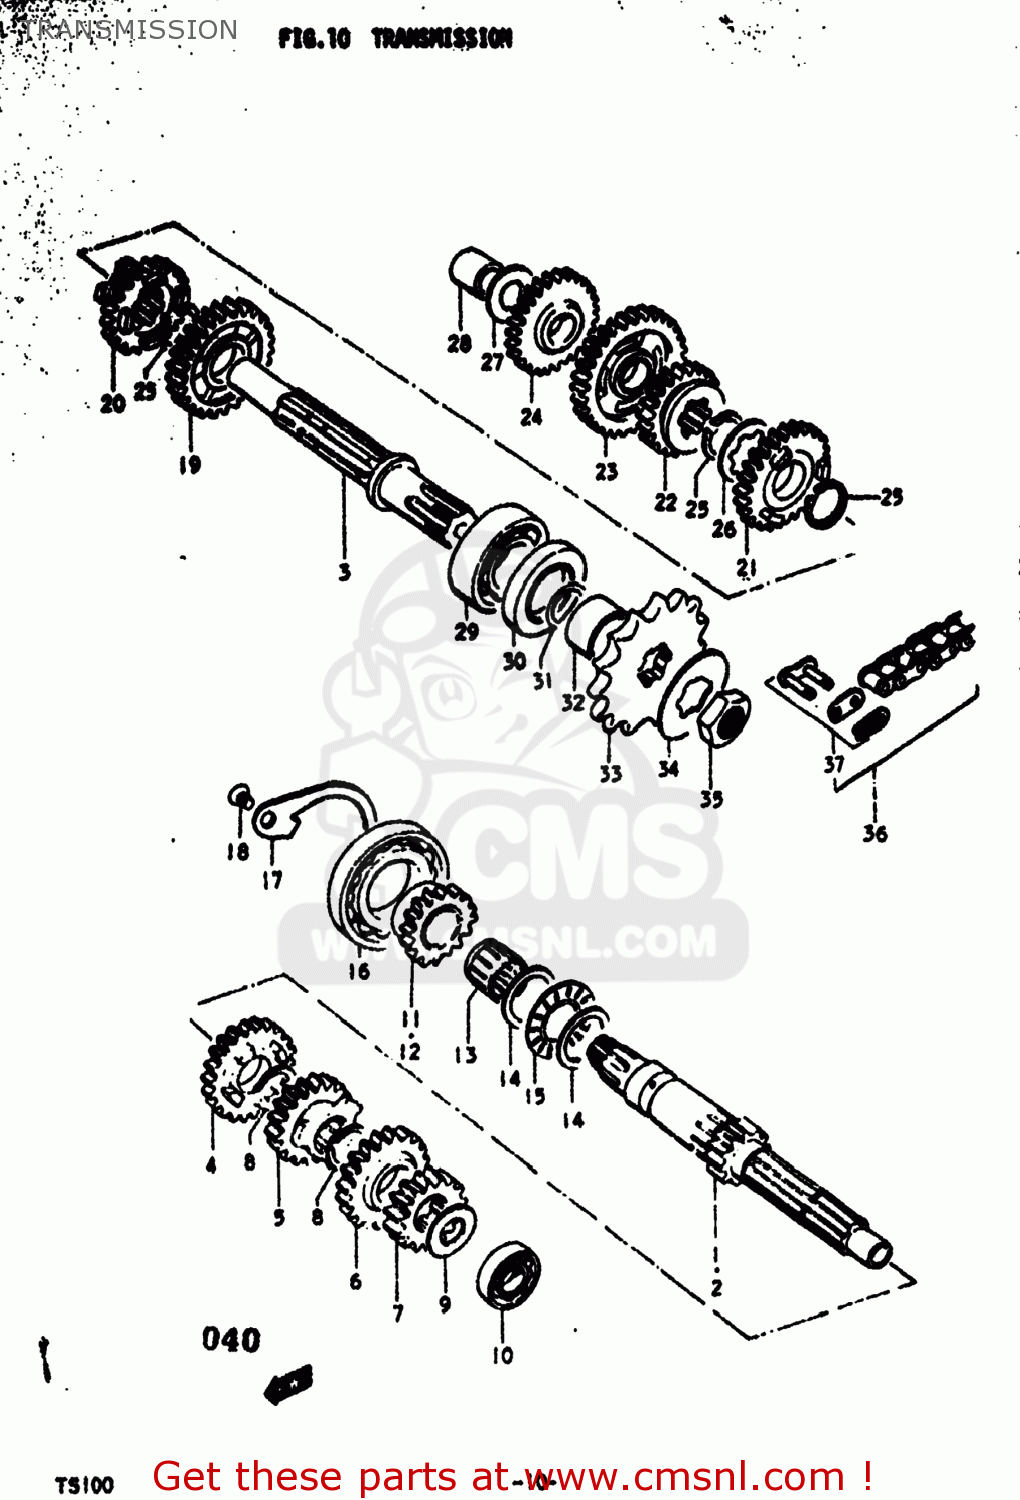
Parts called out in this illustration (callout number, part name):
1	SHAFT,COUNTER
2	SHAFT,COUNTER
3	SHAFT,DRIVE
4	GEAR,FIFTH DRIVE
5	GEAR,THIRD DRIVE
6	GEAR,FOURTH DRIVE
7	GEAR,SECOND DRIVE
8	CIRCLIP
9	WASHER
10	BEARING(12X28X8)
11	GEAR,KICK STARTER DRIVEN(NT:16
12	GEAR,KICK STARTER DRIVE
13	BEARING(19.2X23.2X19)
14	WASHER(21X30X0.8)
15	BEARING 21X35X2.8
16	BEARING
17	PLATE,COUNTERSHAFT BEARING
18	SCREW
19	GEAR,SECOND DRIVEN
20	GEAR,FOURTH DRIVEN
21	GEAR,THIRD DRIVEN
22	GEAR,FIFTH DRIVEN
23	GEAR,FIRST DRIVEN
24	GEAR,KICK STARTER IDLE
25	CIRCLIP
26	WASHER
27	WASHER
28	BUSHING
29	Bearing
30	SEAL,OIL(25X40X7)
31	O RING(D:1,ID:19.5)
32	SPACER (20X25X13.5)
33	SPROCKET,ENGINE
34	WASHER,LOCK
35	NUT
36	CHAIN ASSEMBLY,DRIVE
37	JOINT ASSEMBLY,CHAIN
